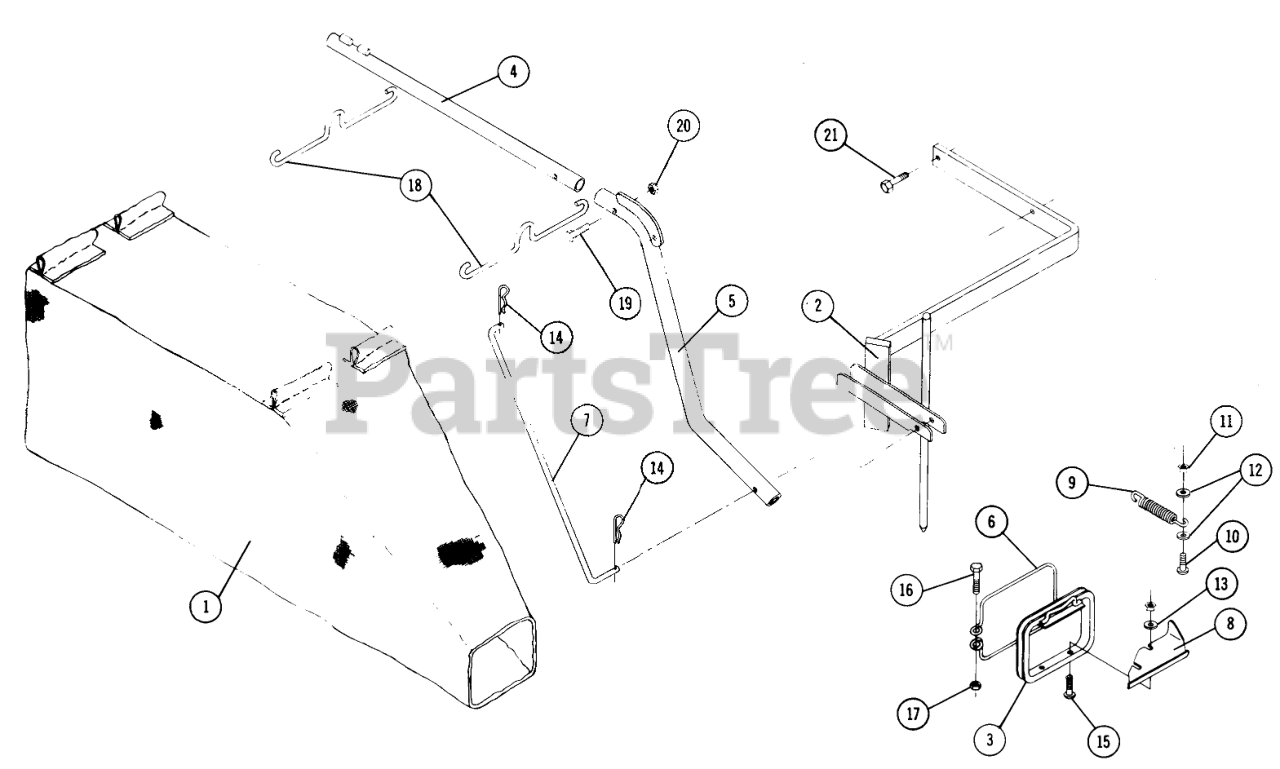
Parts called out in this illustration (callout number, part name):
2	Mounting Bracket
3	Bag Opening Frame
4	Upper Tube
5	Lower Tube
6	Wire Hoop
7	Link
8	Bottom Plate
9	SPRING R
10	Bolt 3/8-16 x 1 Pan Hd.
11	3/8-16 E.S.
12	Washer
13	Washer
14	Hairpin
15	Bolt 1/4-20 x 3/8 PHCR
16	Bolt 1/4-20 x 2
17	Nut-Nylok
18	Hook
19	Bolt 5/16-18 x 11/4
20	Nut-Nylok
21	Bolt 3/8-16 x 1 1/4 Swage
